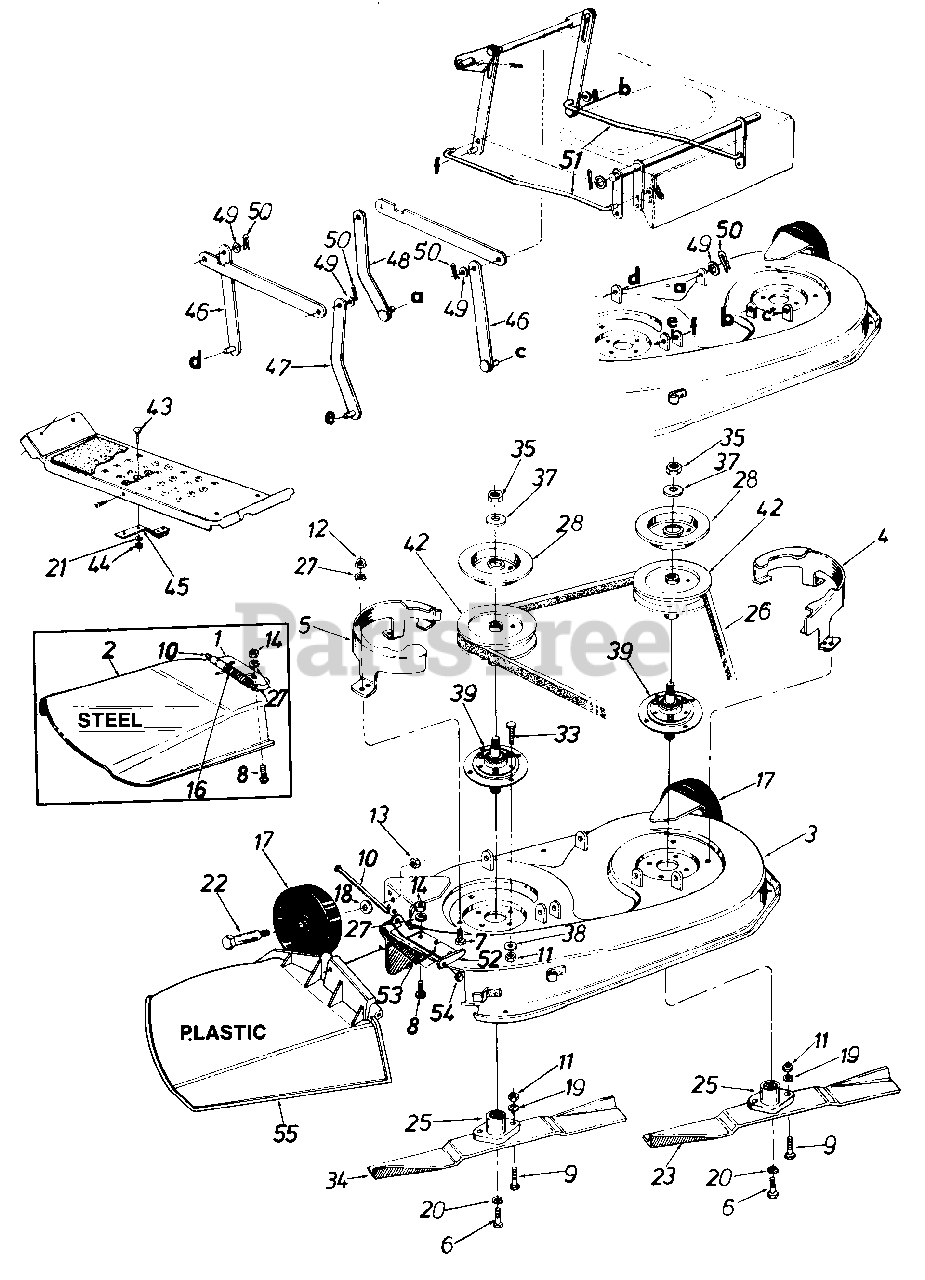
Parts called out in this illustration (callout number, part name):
1	Chute Bracket (Steel)
2	Chute Deflector (Steel)
3	38" Deep Deck Ass'y.
7	Hex Bolt 1/4-28 x .62"
8	Truss Mach. Scr. 1/4-20 x .75"
9	Hex Bolt Special 5/16-24 x 1.0"
10	Hinge Pin
11	Hex Nut 5/16-24 Thd.
12	Hex Nut 1/4-28 Thd.
13	Hex Top L-Nut 3/8-16 Thd.
14	Hex Jam Nut 1/4-20 Thd.
16	Torsion Spring
17	Deck Wheel-5"
18	Bell-Wash. .40" I.D. x .88" O.D.
19	L-Wash. 5/16" I.D.
20	L-Wash. 3/8" I.D.-H.D.
21	L-Wash. 1/4" I.D.
22	Shld. Bolt .498" Dia. x 1.53"
23	High-Lift Blade
25	Blade Adapter
26	5L V-Belt
27	Bell-Wash. 1/4" I.D.
28	Brake Disc
33	Rib Neck Bolt 5/16-24 x 1.05" Lg.
34	High-Lift Blade
35	Hex Jam Nut 5/8-18 Thd.
37	L-Wash. 5/8" I.D.
38	L-Wash. 5/16" I.D.
39	Blade Spindle Ass'y. Comp.
42	5" Dia. Pulley
43	Carr. Bolt 1/4-20 x .62"
44	Hex Nut 1/4-20 Thd.
45	Blade Brake Ass'y
46	Link Deck Hanger Assy
47	Link Deck Hanger Ass'y.
50	Inter. Cotter Pin .50" Dia.
51	Stabilizer Rod
52	Hinge Mtg. Brkt.
53	Torsion Spring
54	Push Nut
55	Chute Ass'y. Comp. (Plastic)
